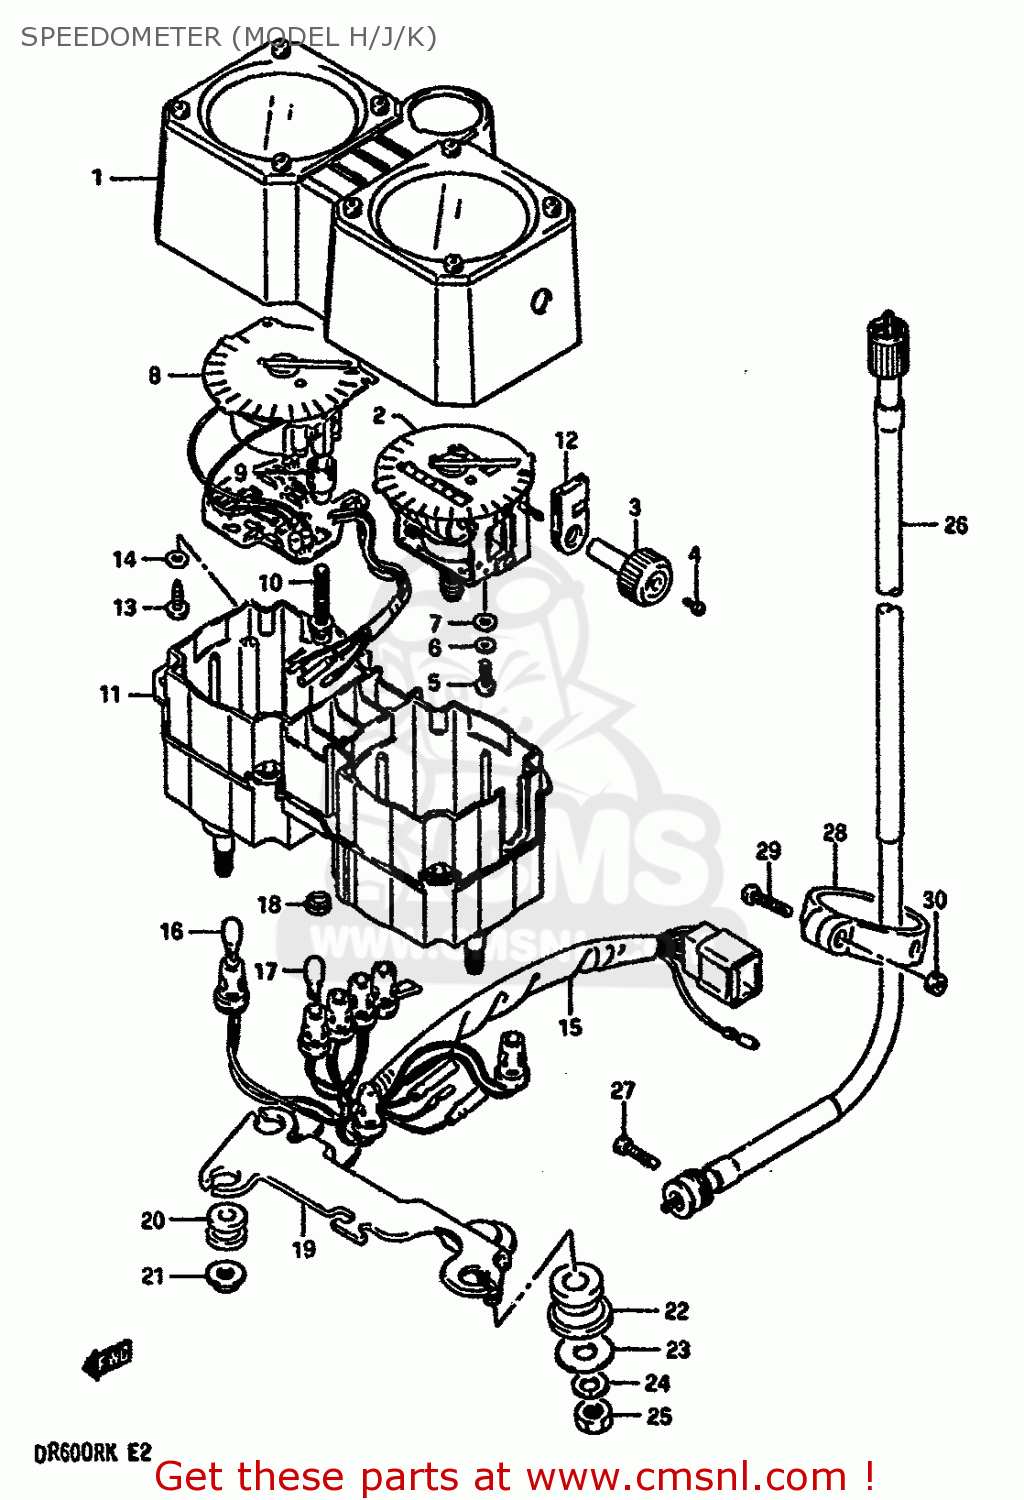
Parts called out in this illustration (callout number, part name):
1	HOOD,METER
2	SPEEDOMETER
3	KNOB,TRIP
4	SCREW,TRIP KNOB
5	SCREW
6	LOCK WASHER
7	WASHER 3.3X8X0
8	TACHOMETER
9	SPACER
10	SCREW
11	CASE,METER
12	CUSHION,METER
13	SCREW
14	LOCK WASHER
15	SOCKET,METER
16	BULB(12V1.7W,WB372,T7)
17	BULB(12V3W,WB371,T7)
18	CAP
19	BRACKET,METER
20	CUSHION,METER
21	NUT
22	CUSHION,METER BRACKET
23	WASHER (8.5X20X1.6)
24	WASHER,LOCK,8.
25	NUT
26	CABLE ASSEMBLY,SPEEDOMETER
27	BOLT
28	CLAMP,SPEEDOMETER CABLE
29	SCREW 5X20
30	NUT
